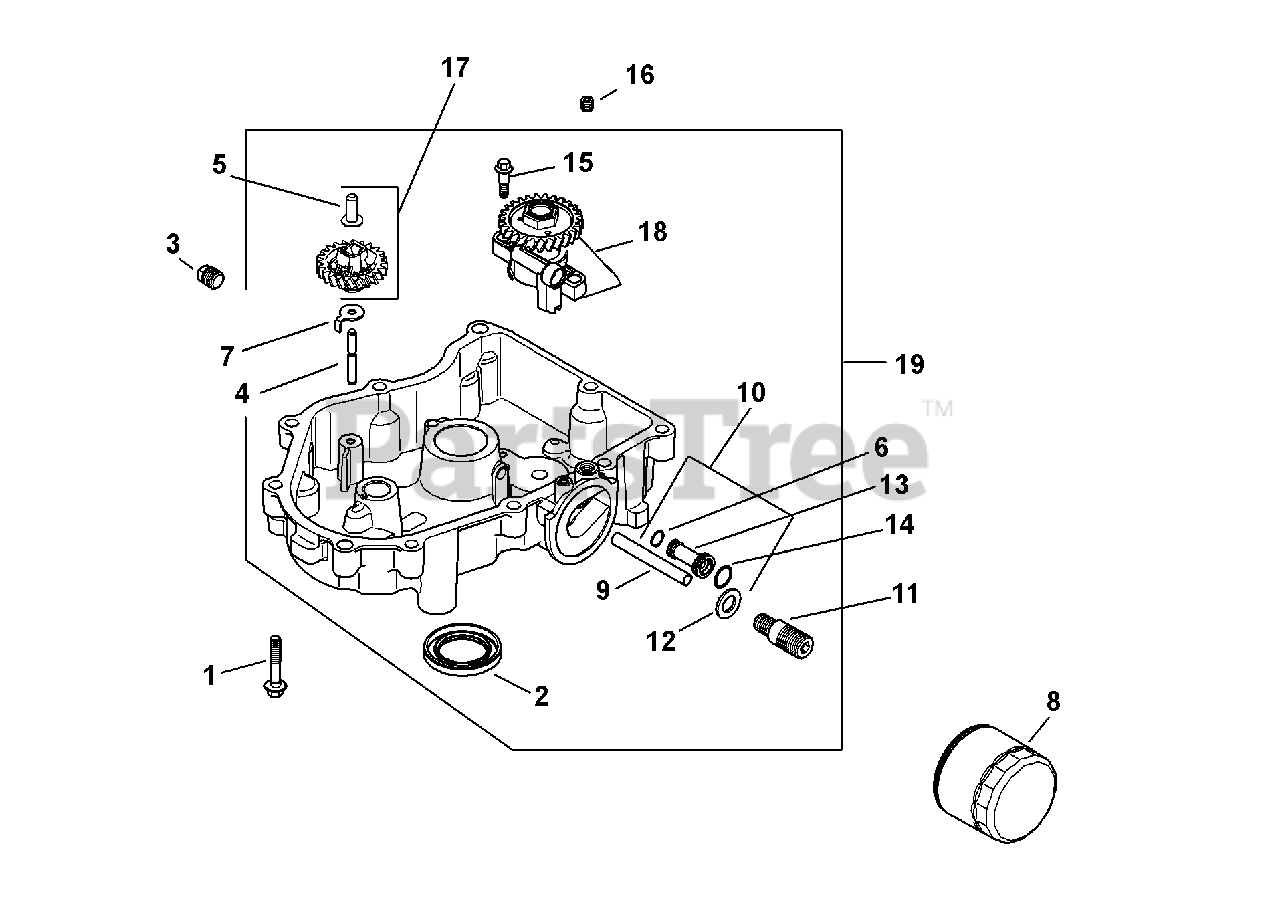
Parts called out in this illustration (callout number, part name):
1	Flg. Screw, M8 x 1.25 x 45
3	Sq. Hd. PipePlug, 3/8
4	Governor Gear Shaft
5	Governor Regulating Pin
6	Oil Pick-Up O-Ring
9	Oil Feed Tube - Filter To Pan
10	Oil Feed Tube Assembly
11	Oil Filter Nipple
13	Oil Feed Tube
15	Shd. Thd. Frm. Screw, M6 x .0 x 6.5
16	Pipe Plug, 1/8"
17	Governor Gear Kit (Inc. 5)
18	Oil Pump Assembly
19	Oil Pan Assembly
